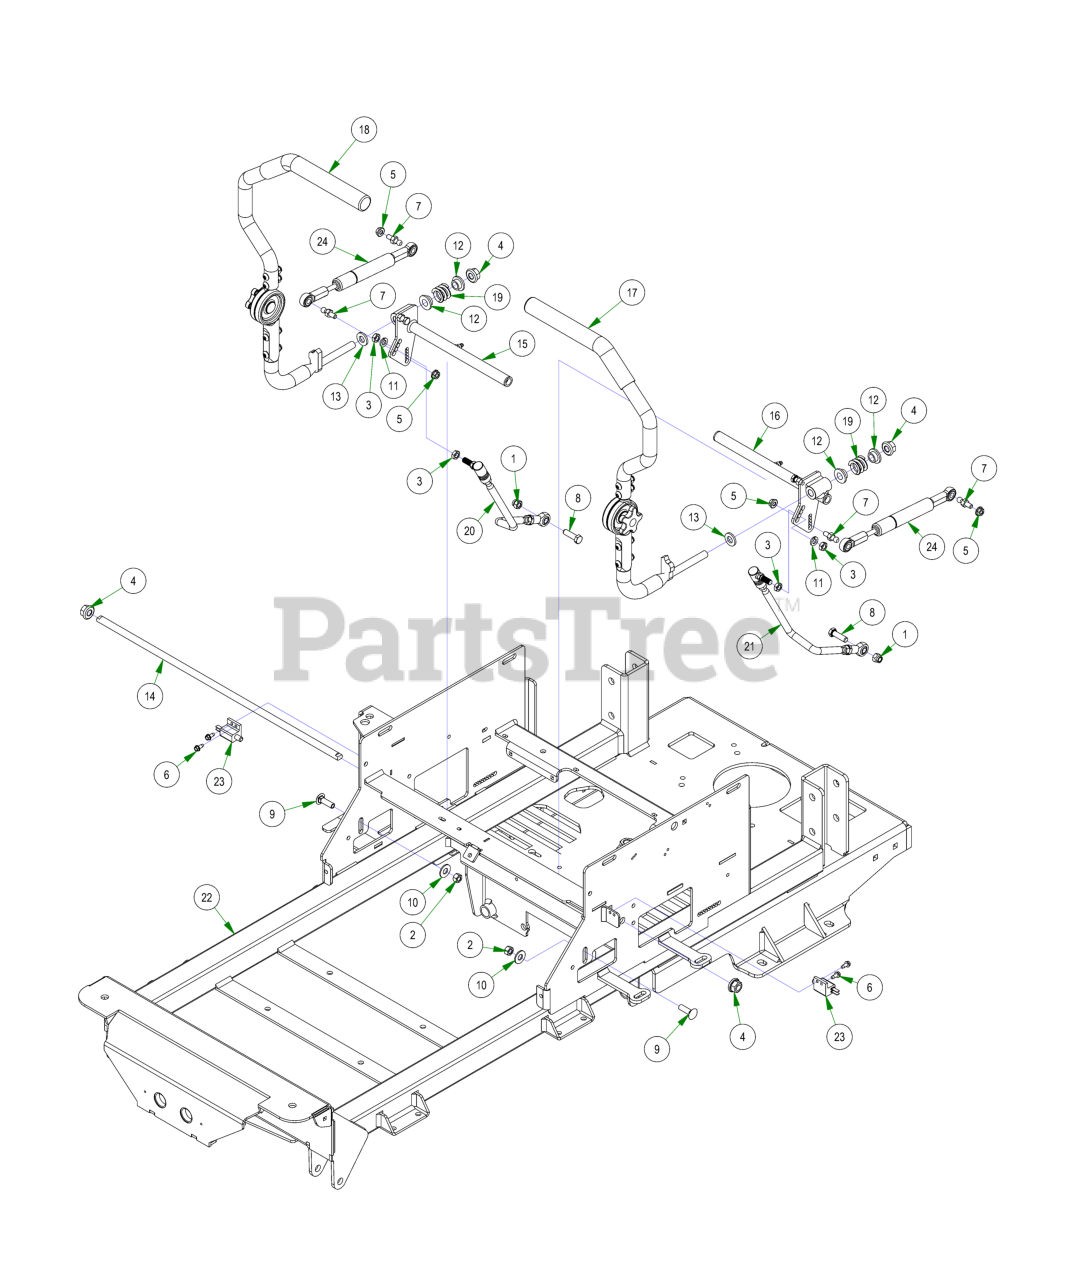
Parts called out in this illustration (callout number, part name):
1	3/8-16 NYLON INSERT LOCKNUT ZINC
2	3/8-16 HEX NUT ZINC
3	3/8-24 HEX NUT ZINC YELLOW
4	1/2-13 NYLON INSERT FLANGE LOCKNUT ZINC
5	5/16-18 HEX SERRATED FLANGE NUT HARD/ZINC
6	12-24 X 1/2 HEX WASHER UNLSOT F TCS ZINC
7	10mm Damper Ball Stud-Steering
8	3/8-16 X 1-1/4 HEX CAP SCREW (GR.5) ZINC
9	3/8-16 X 1-1/4 CARRIAGE BOLT ZINC
10	3/8 FLAT WASHER USS (1" OD) ZINC
11	3/8 SPLIT LOCKWASHER ZINC
12	.525 ID SHOULDER WASHER NYLON
13	.505 ID X 1.000 OD X .125 THICK FLAT WASHER NYLON
14	2021 Maverick Steering Actuator Rod
15	2021 Maverick Drive Arm Actuator RH Assembly
16	2021 Maverick Drive Arm Actuator LH Assembly
17	2018 Adjustable Steering Arm - Left
18	2018 Adjustable Steering Arm - Right
19	Drive Lever Spring
20	Push Rod-Right
21	Push Rod-Left
22	2023 Maverick Frame - Painted
23	Safety Switch
24	Steering Damper
